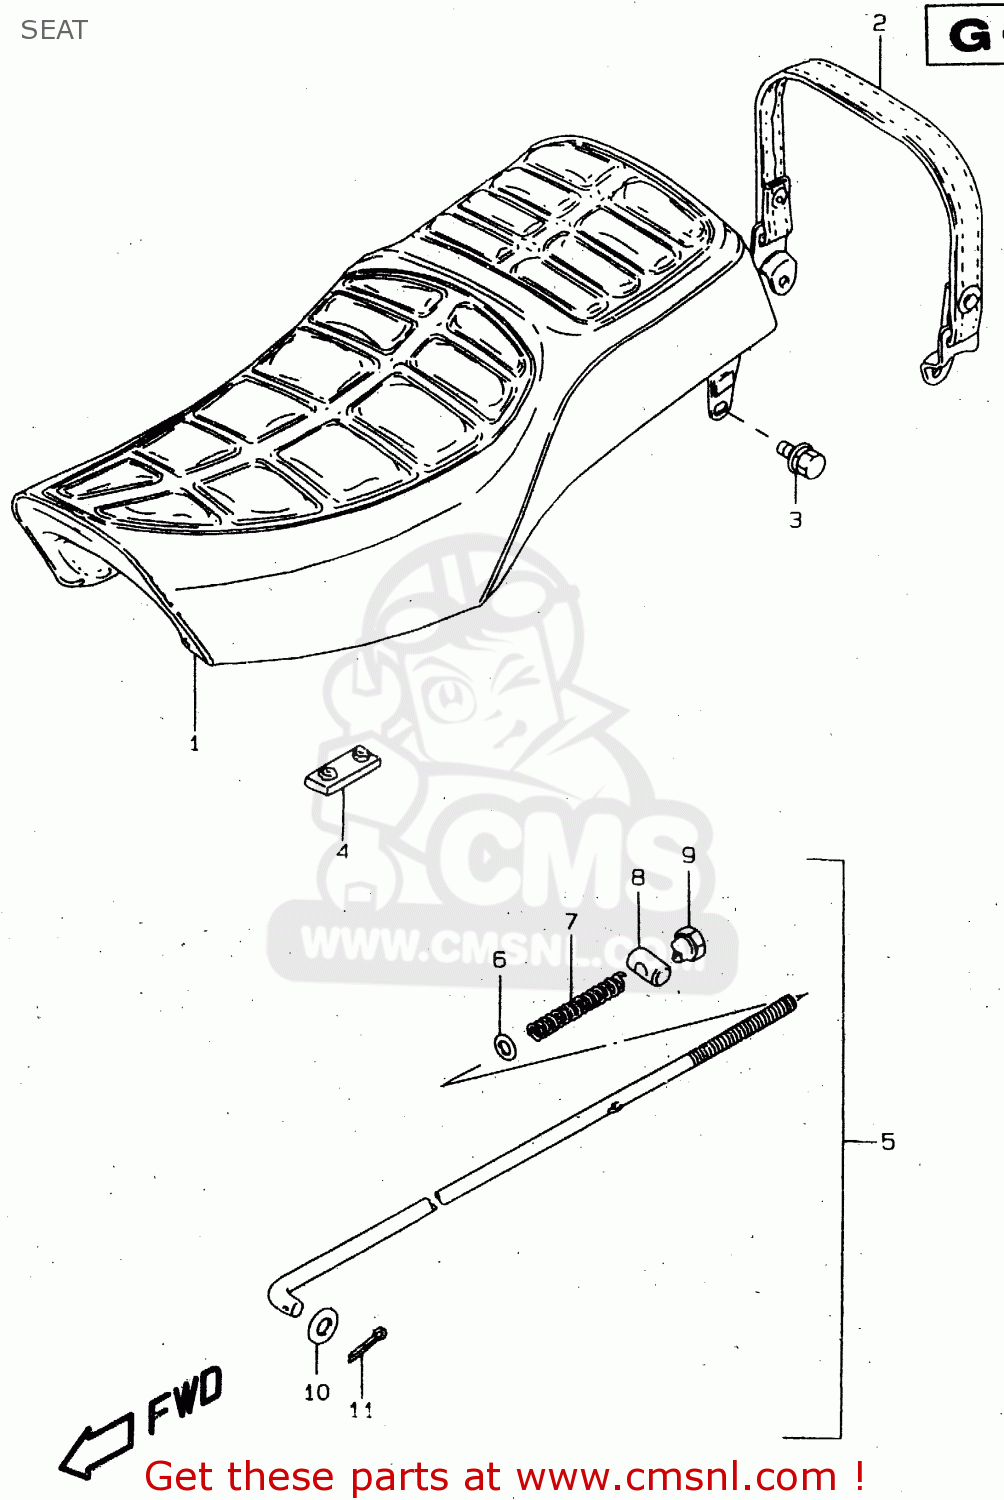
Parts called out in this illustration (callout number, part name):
1	SEAT ASSY
2	BAND,SEAT GRIP
3	BOLT
4	CUSHION
5	ROD ASSY,RR BRAKE
6	WASHER
7	SPRING
8	PIN(13X18)
9	NUT
10	WASHER
11	PIN 20X20
